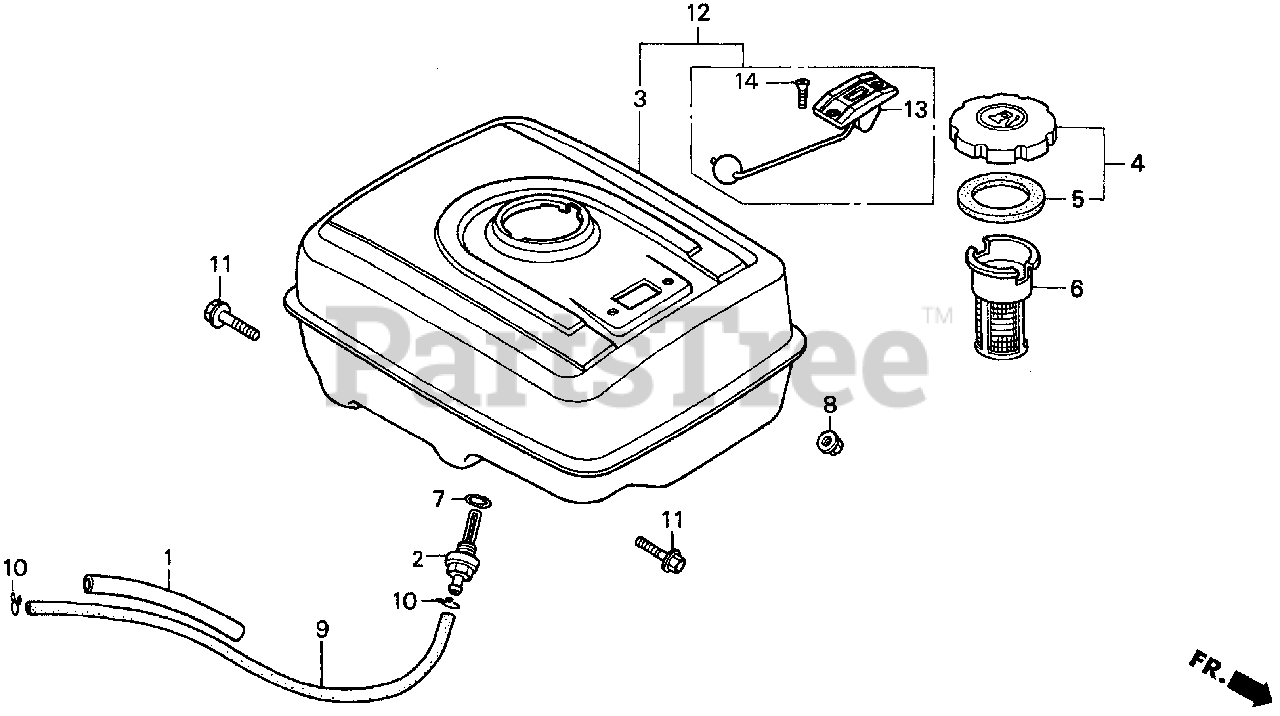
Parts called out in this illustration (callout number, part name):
1	RUBBER, SUPPORTER (107MM)
2	JOINT, FUEL TANK
3	TANK, FUEL *NH31* (MCKINLEY WHITE)
4	CAP, FUEL FILLER
5	GASKET, FUEL FILLER CAP
7	O-RING (13.5X1.5) (ARAI)
8	NUT, FLANGE (8MM)
9	BULK HOSE, FUEL (4.5X3000) (4.5X235)
10	CLIP, TUBE (B8)
11	BOLT, FLANGE (8X25)
